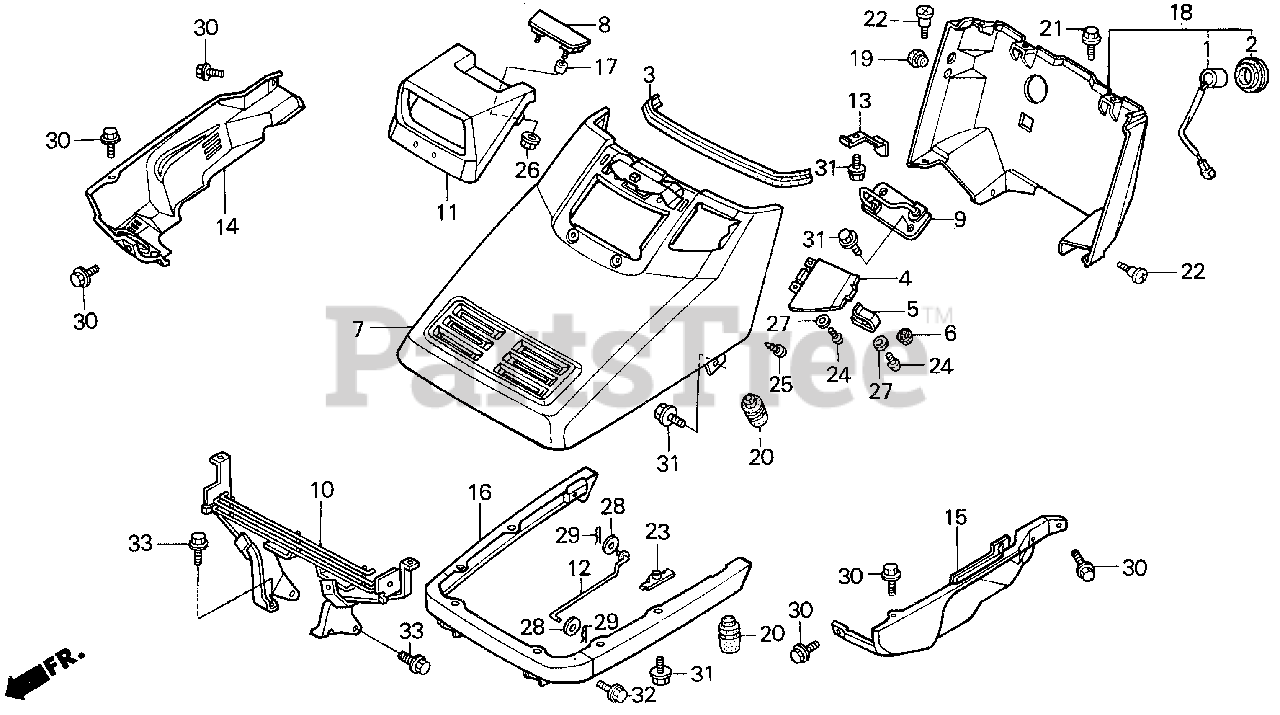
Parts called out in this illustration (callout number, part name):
1	BUZZER, WARNING
2	GROMMET, PARKING BRAKE BUZZER
3	RUBBER, HOOD SEAL
4	LID, FUEL FILLER *R136* (DIANA RED)
5	SPRING, FUEL LID
6	RUBBER, FUEL LID STOPPER
7	HOOD *R136* (DIANA RED)
8	HANDLE, HOOD *NH105* (MAT BLACK)
9	STRIKER, HOOD LOCK
10	BRACKET, HOOD HINGE
11	CASE, HEADLIGHT *NH105* (MAT BLACK)
12	STOPPER, HOOD OPEN
13	SPRING, HOOD LOCK
14	COVER, R. ENGINE ROOM *R136* (DIANA RED)
15	COVER, L. ENGINE ROOM *R136* (DIANA RED)
16	SUPPORT *NH105* (MAT BLACK)
17	COLLAR, FR. FENDER
18	COVER ASSY., STEERING COLUMN *NH105* (MAT BLACK)
19	GROMMET, DRAIN HOLE
20	STOPPER, TAILGATE (BLACK)
21	BOLT, FLANGE (6X12)
22	SCREW, METER VISOR SETTING
23	NUT, PLATE
24	SCREW, PAN (5X8)
25	SCREW, TAPPING (5X12)
26	NUT, FLANGE (5MM)
27	WASHER, PLAIN (5MM)
28	WASHER, PLAIN (6MM)
29	PIN, LOCK (6MM)
30	BOLT, FLANGE (6X12)
31	BOLT, FLANGE (6X10)
32	BOLT, FLANGE (8X16)
33	BOLT, FLANGE (10X22)
